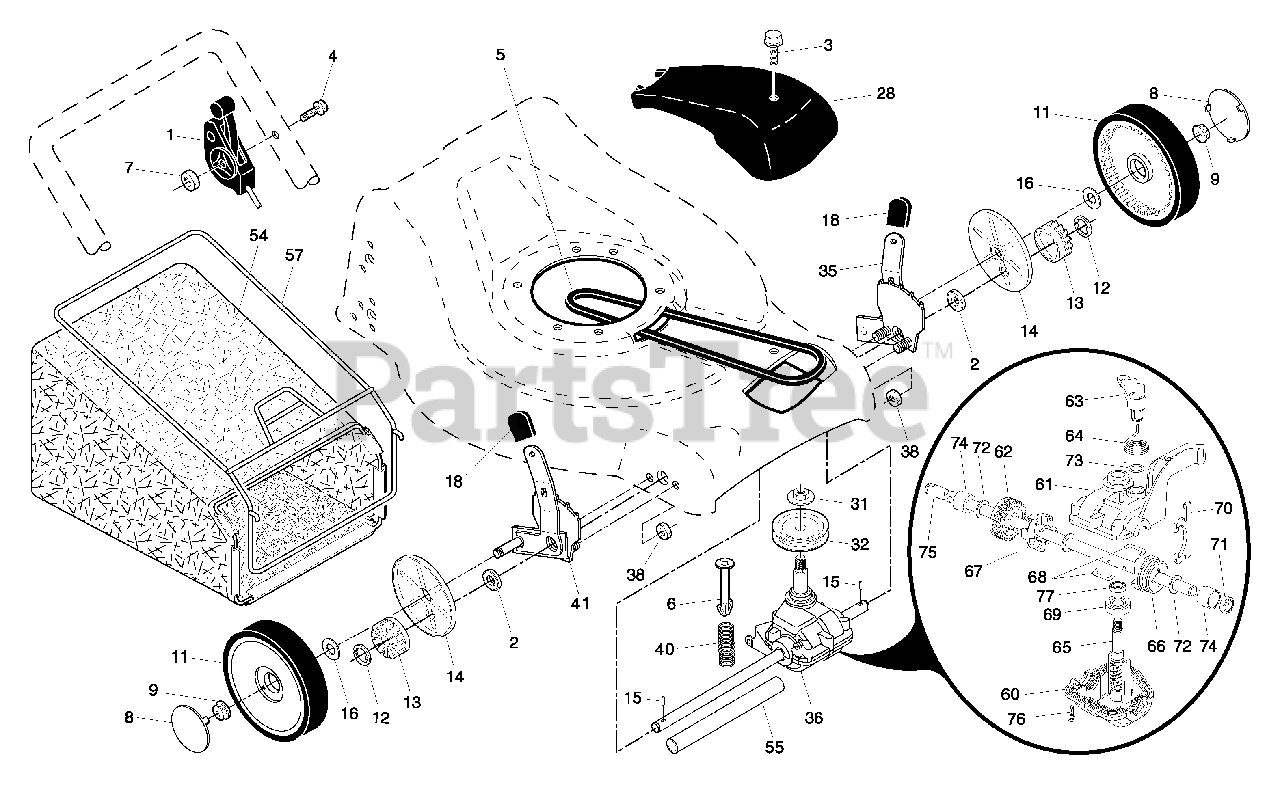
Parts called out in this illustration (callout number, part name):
1	Drive Control Assembly
2	Bearing, Wheel Adjuster
3	Pan Head Tapping Screw #10-24 x 2-3/4
6	Retainer, Spring
7	Nut, Hex, Flanged 1/4-20
8	Hubcap
9	Locknut
11	Wheel & Tire Assembly
13	Pinion
14	Dust Cover
15	Pawl, Drive
16	Washer 1/2
18	Selector Knob
28	Drive Cover
31	Hex Flange Nut
32	Pulley, Drive
35	Kit, Wheel Adjuster, LH
36	Gear Case Assembly, Complete
38	Locknut 1/4-20
40	Spring, Tension
41	Kit, Wheel Adjuster, RH
54	Grassbag Assembly
55	Driveshaft Cover
57	Frame, Grassbag
60	Case, Lower
61	Case, Upper
62	Gear, 27 Teeth
63	Lever, Clutch
64	Spring, Return
65	Shaft, Input
66	Dog, Movable
67	Dog, Fixed
68	Wire, Formed
69	Bearing, Ball
70	Fork, Shift
71	Seal, Output Shaft
73	Seal, Case
75	Shaft, Output
77	Seal, Input Shaft
